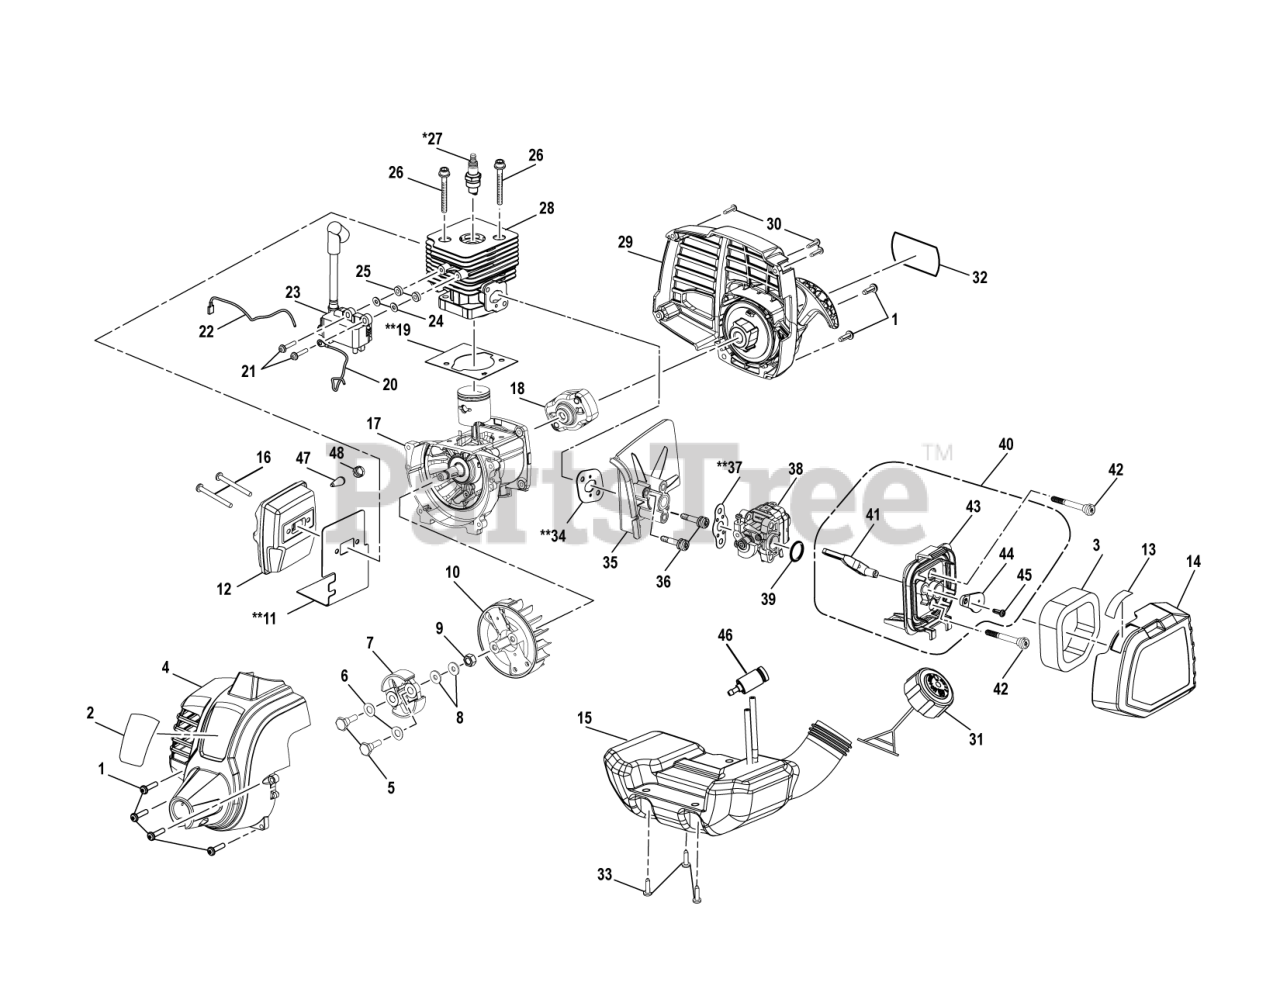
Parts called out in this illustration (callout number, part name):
1	SCREW W/WASHER
2	LABEL, LOGO
3	FILTER, AIR
4	ASSY., FRONT HOUSING
5	BOLT, CLUTCH SHOULDER
6	WASHER, CURVED
7	ASSY., CLUTCH
9	NUT, HEX FLANGE
10	FLYWHEEL
11	GASKET, MUFFLER
12	ASSY., MUFFLER
13	LABEL, CHOKE POSITION
14	COVER, AIRBOX
15	ASSY., FUEL TANK W/CAP
17	ASSY., CRANKCASE
18	CUP, STARTER
20	WIRE, LEAD (RED)
21	SCREW W/WASHER
22	WIRE, LEAD (BLACK)
23	MODULE, IGNITION
27	PLUG, SPARK (LTRTC)
28	CYLINDER
29	ASSY., STARTER
31	ASSY., FUEL CAP
32	LABEL, LOGO (REAR)
33	SCREW, SHOULDER
34	GASKET, INSULATOR
35	INSULATOR, HEAT DAM
38	ASSY., CARBURETOR
39	O-RING, CARBURETOR
40	ASSY., AIRBOX BASE
41	LEVER, CHOKE
43	BASE, AIRBOX
44	PLATE, CHOKE
46	FILTER FUEL
47	KIT, HONDA WT SPARK ARRESTOR
48	KIT, BRIGGS 208CC SPRK ARRESTR
